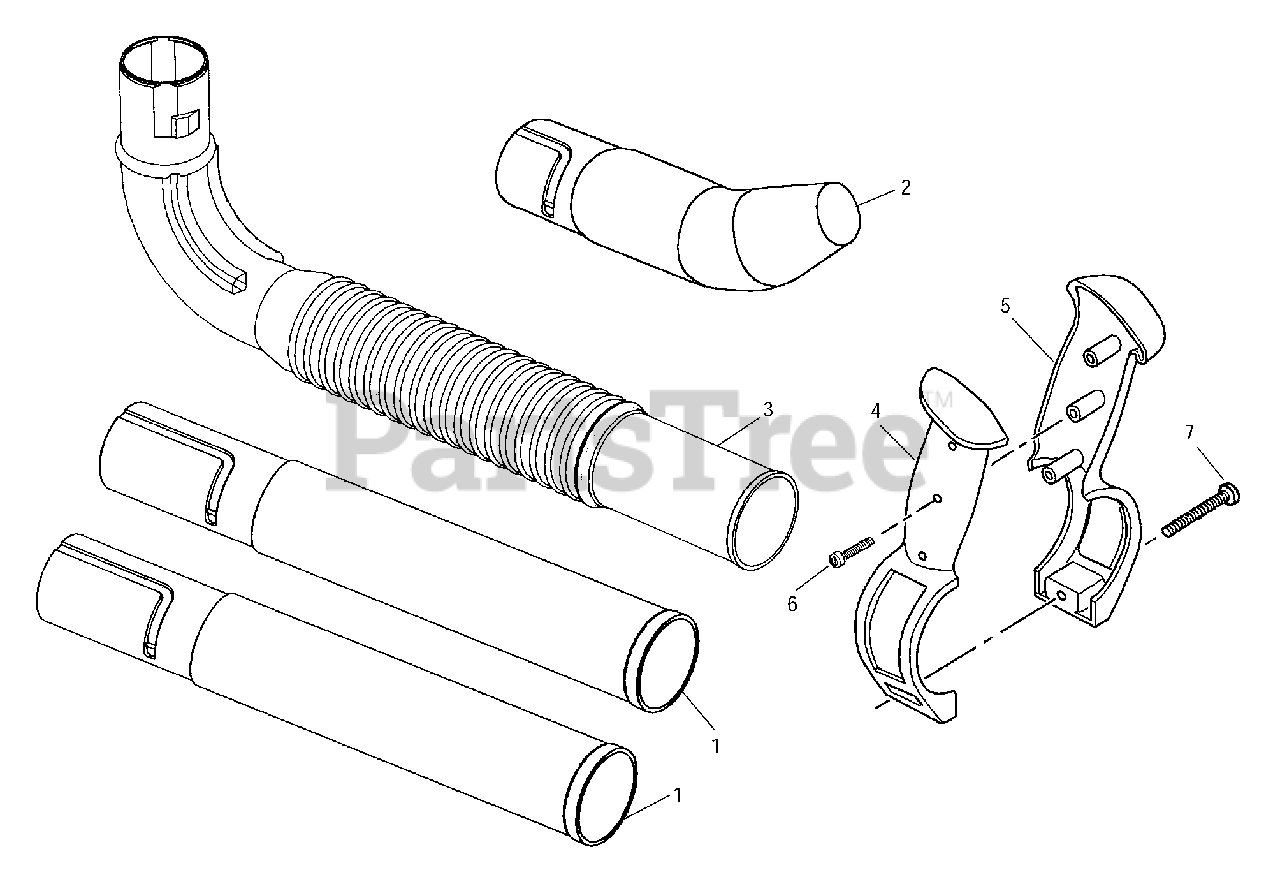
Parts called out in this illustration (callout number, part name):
1	Tube, Air
2	Nozzle, Concentator Outlet
3	Elbow, Flex Tube
4	Handle, Tube, RH
5	Handle, Tube, LH
6	Screw, 6-19x.62Fl Hd Plast
7	Screw, 12-14x1.5 Torx
